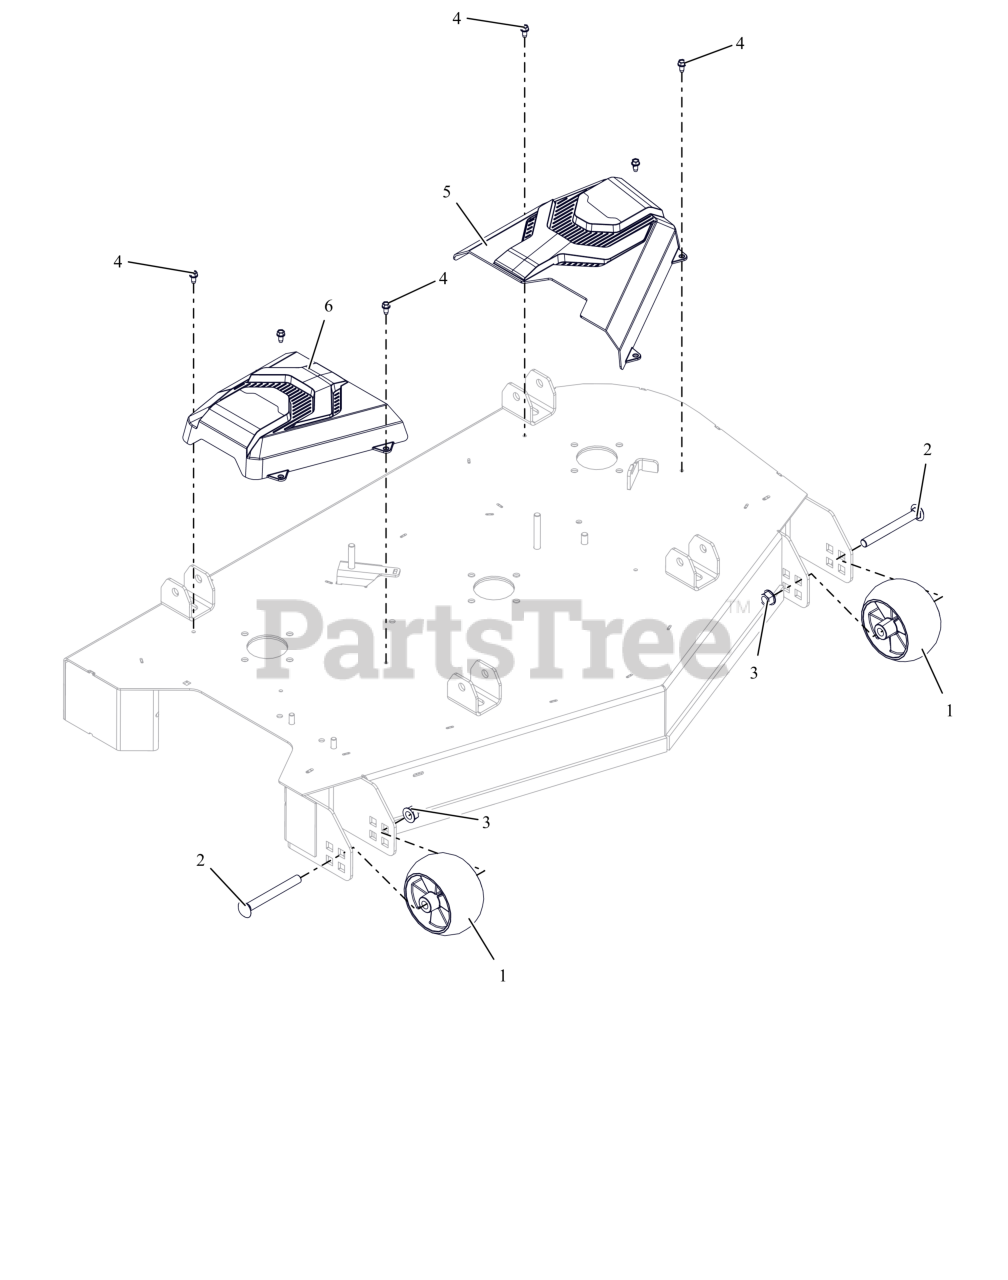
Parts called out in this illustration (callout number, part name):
1	WHEEL, ANTI SCALP - 5X3 CTR W/RIBS
2	BLT-RHNS .50-13X4.50 G5 ZCC NS
3	NUT-LK-CTR-FLG .500-13 GG ZCC
4	SCR-TAP .25-20X.50 HWH ZCC
5	COVER- BELT LH
6	COVER- BELT RH
